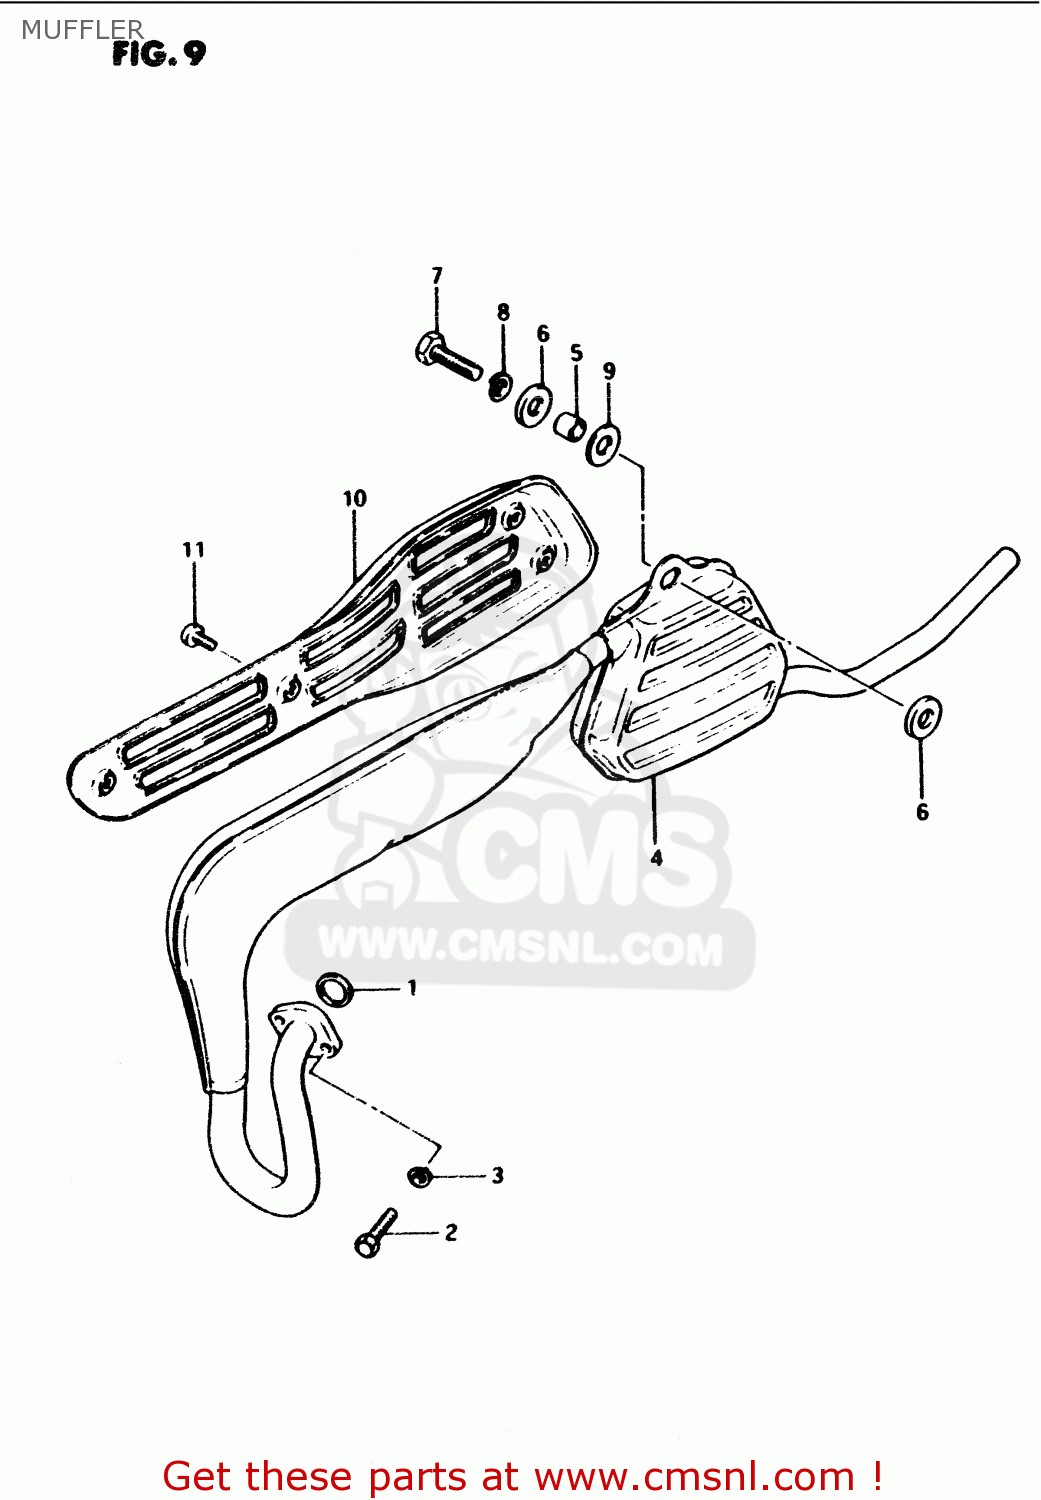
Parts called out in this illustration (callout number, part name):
1	GASKET,EXHAUST (NAS)
2	BOLT
3	WASHER,LOCK
4	MUFFLER
5	SPACER (8.6X13.8X8)
6	CUSHION
7	BOLT
8	LOCK WASHER
9	WASHER
10	COVER,MUFFLER
11	SCREW
